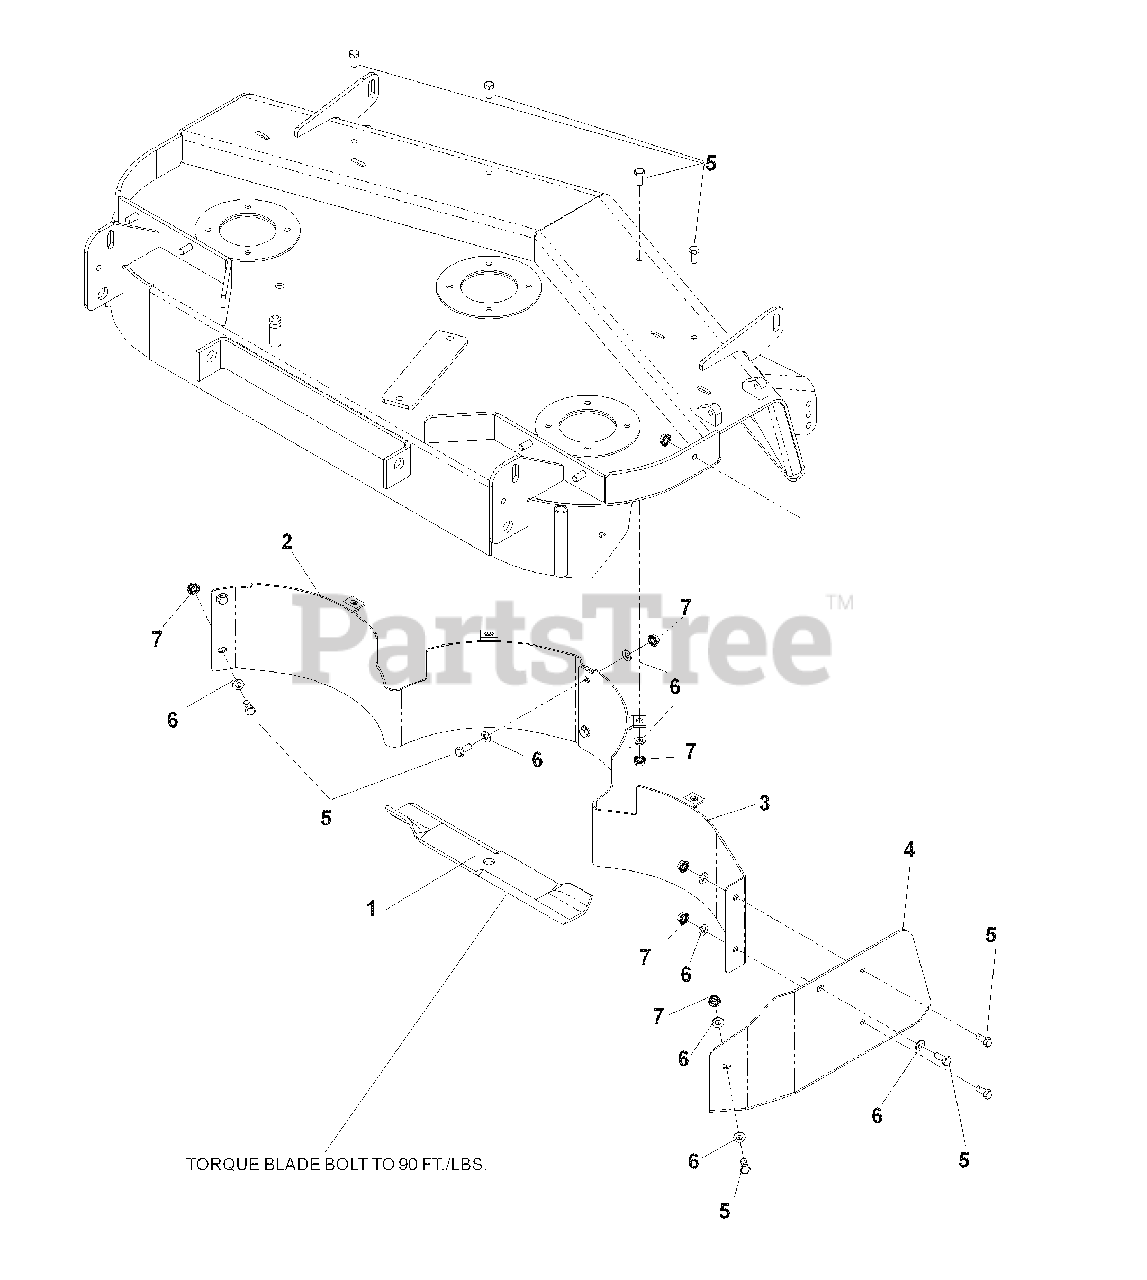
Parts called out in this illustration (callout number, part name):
1	42" MULCH BLADE, 14 7/8"
2	MULCH BAFFLE, LEFT, 42"
3	MULCH BAFFLE, RIGHT, 42"
4	MULCH CAP, 42"
5	HCS, 5/16-18 x 3/4
6	WASHER, 5/16, SAE
7	NUT, 5/16 -18, WHIZLK
